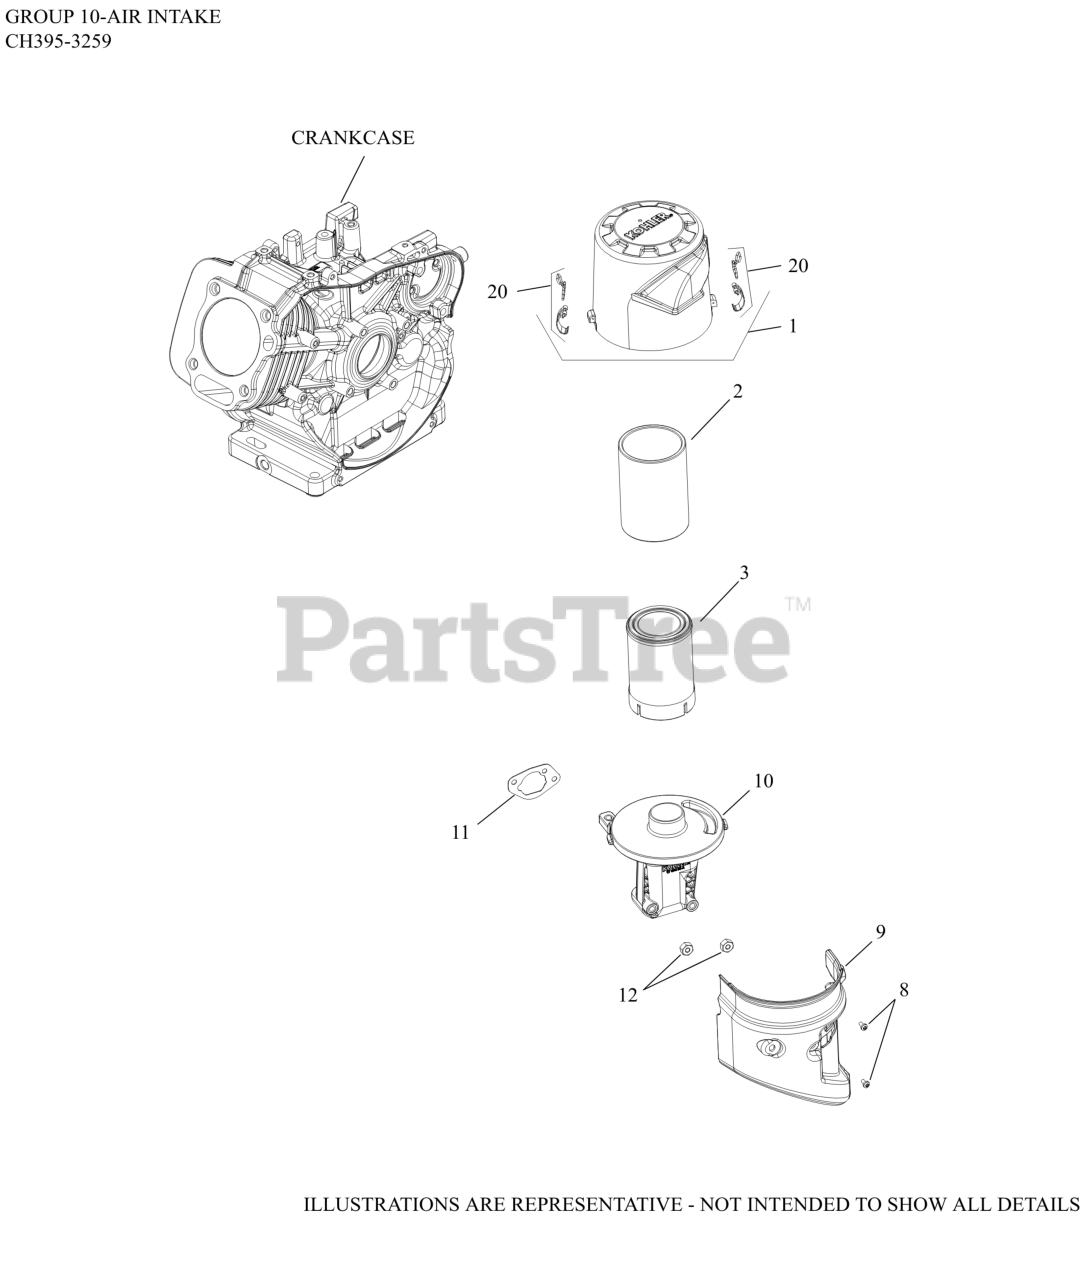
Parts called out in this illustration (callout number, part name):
1	COVER, AIR CLEANR ASSEMBLY
2	ELEMENT, PRE-CLEANER
3	ELEMENT, AIR FILTER
8	SCREW,COVR TO BLWR HOUSING
9	COVER, A/C BASE CH395
10	AIR CLEANER BASE ASSY
11	GASKET, AIR CLEANER
12	NUT, HEX (M6 THREAD, M8 BODY)
20	KIT, LATCH CLIP
